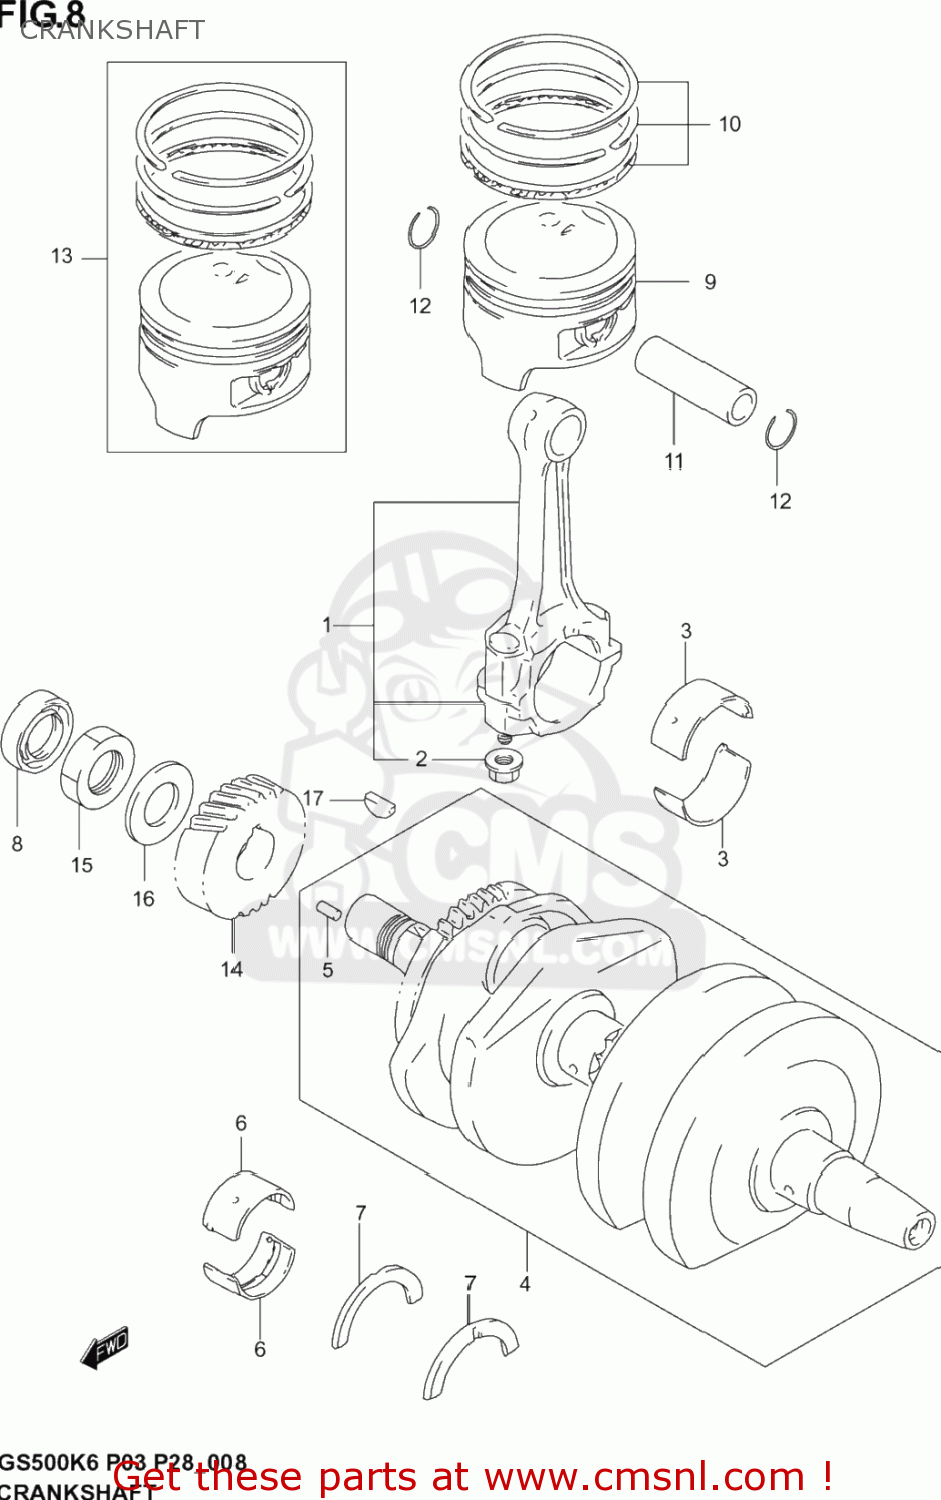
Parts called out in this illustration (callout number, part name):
1	ROD ASSEMBLY,CONNECTING
2	NUT
3	BEARING,CRANK PIN
4	CRANKSHAFT
5	PIN
6	BEARING,CRANKSHAFT(GREEN)
7	BEARING,CRANK THRUST
8	SEAL,OIL(22X40X8)
9	PISTON (74.00MM)
10	RING SET,PISTON
11	PIN,PISTON (18MM)
12	CIRCLIP
13	PISTON SET(OS:0.5)
14	GEAR,PRIMARY DRIVE NO.28
15	NUT
16	WASHER
17	KEY
